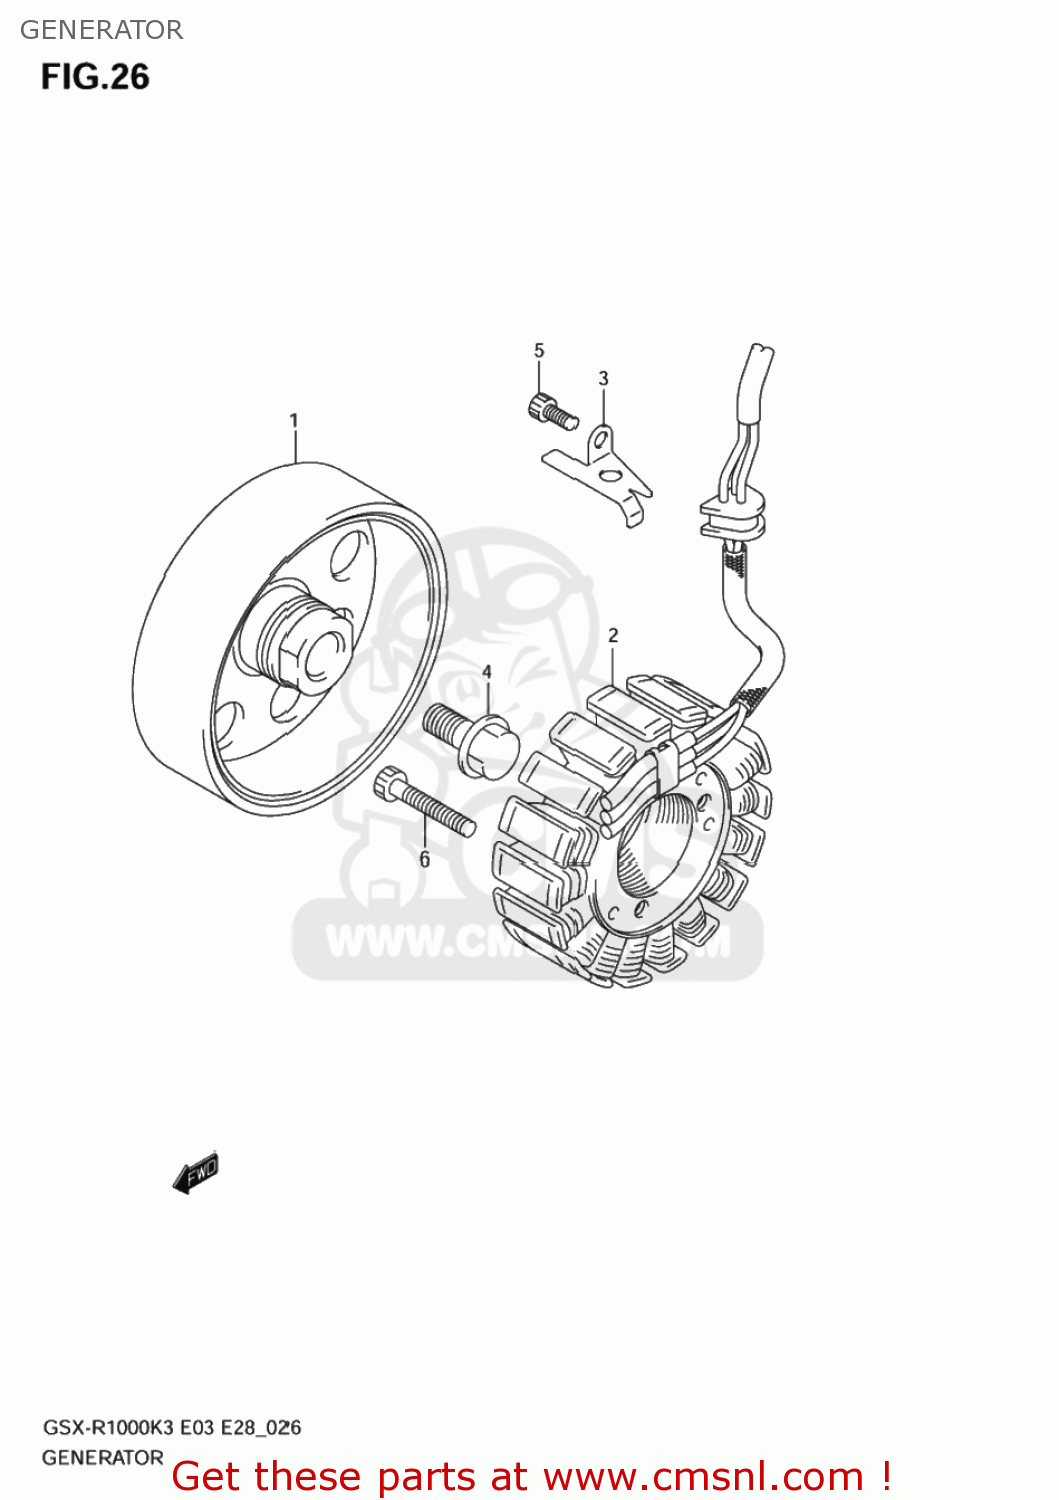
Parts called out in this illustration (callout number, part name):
1	ROTOR ASSY
2	STARTER ASSY
3	CLAMP,MAGNETO LEAD
4	BOLT(12X23)
5	BOLT,STRANGER
6	BOLT
